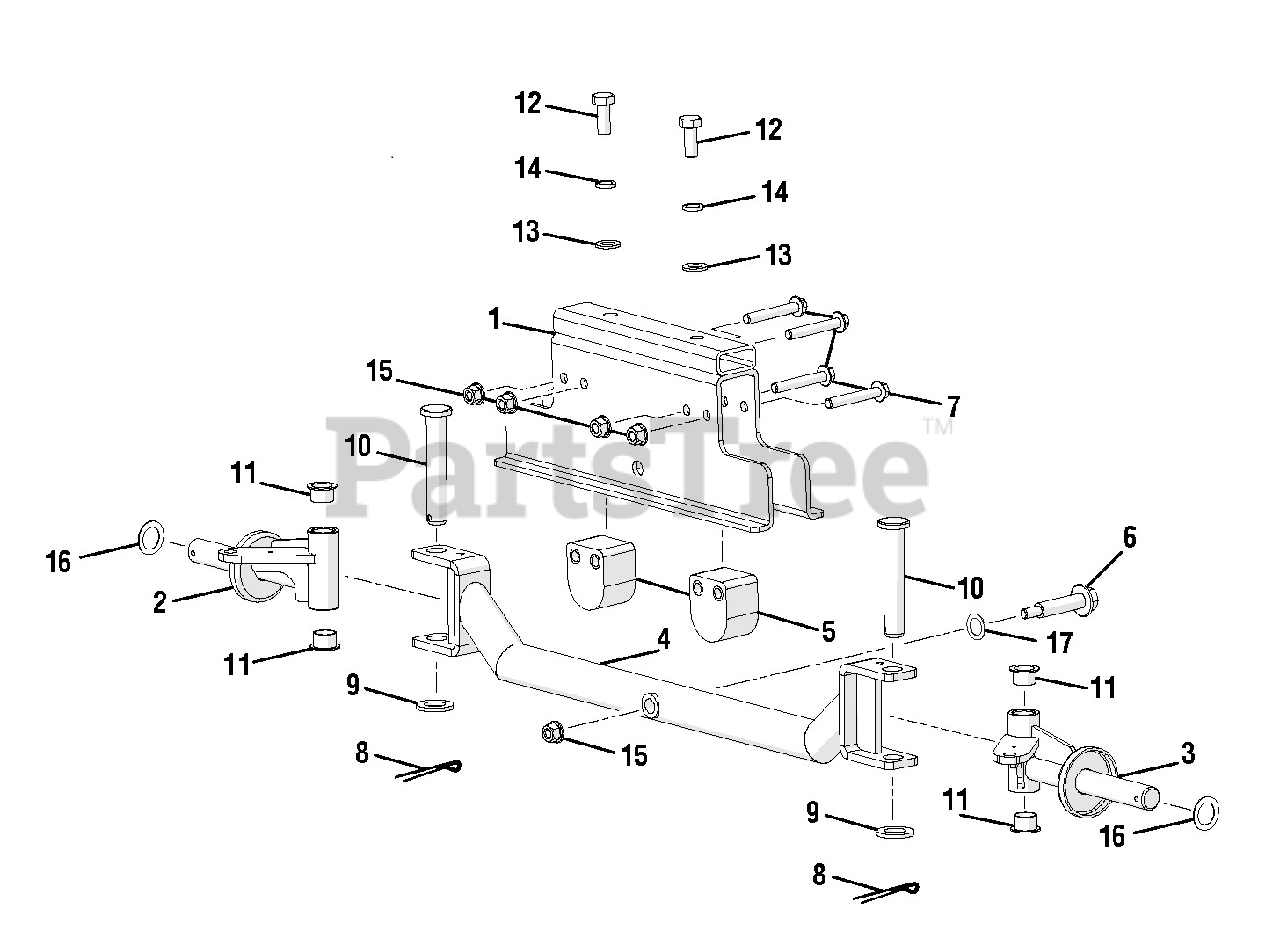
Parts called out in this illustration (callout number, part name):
1	Front Axle Channel Plate w/Brackets
2	Right Steering Knuckle
3	Left Steering Knuckle
4	Front Axle
5	Front Axle Rubber Bumper Assembly
6	Shoulder Bolt (M8 x 60 mm, Flange Hex Hd.)
7	Bolt (M8 x 55 mm, Flange Hex Hd.)
8	Cotter Pin (4 x 40)
9	Washer (OD30 x ID17 x 3t)
10	Steering Knuckle Anchor
11	Steering Knuckle Bushing
12	Bolt (M10 x 45 mm, Hex Hd.)
13	Washer (OD20 x ID10.5 x 2t)
14	Lock Washer (M10)
15	Flange Nut (M8)
16	Washer (OD28 x ID20.5 x 2t)
17	Washer (OD24 x ID13 x 2.5t)
